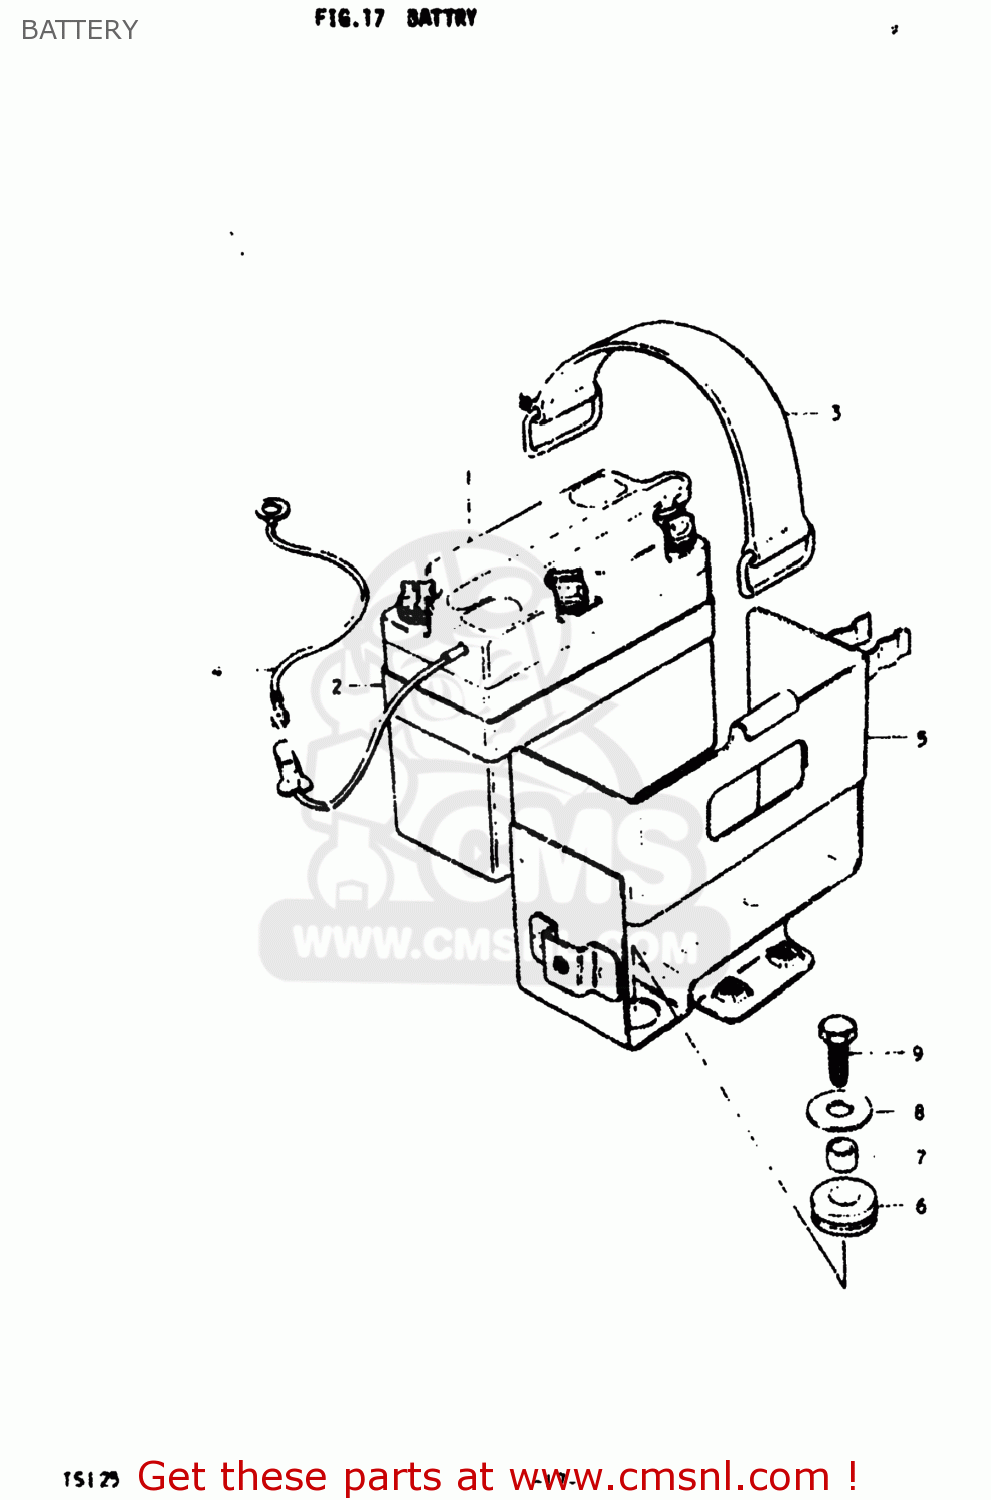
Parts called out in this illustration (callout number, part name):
1	BATTERY(6N4B-2A,6V4.2AH)
2	PROTECTOR,BATTERY
3	BAND
4	LEAD WIRE
5	HOLDER,BATTERY
6	CUSHION
7	SPACER (7X9X7)
8	WASHER (6.5X20X1.2)
9	BOLT, UPPER
